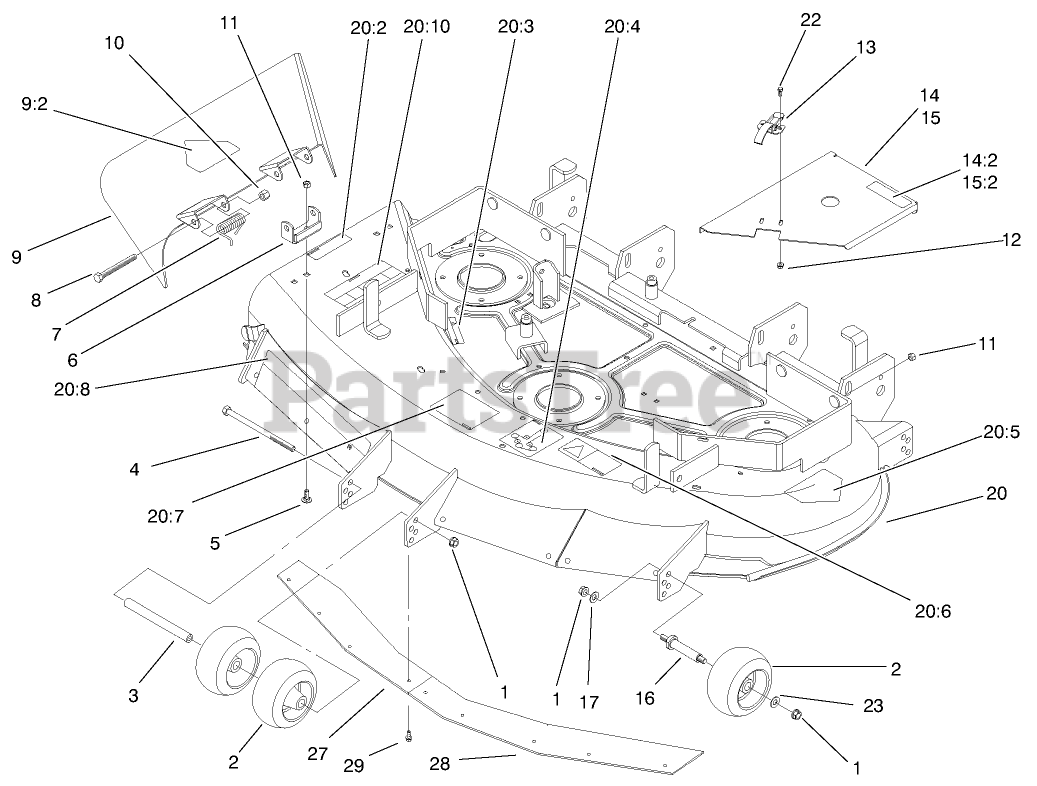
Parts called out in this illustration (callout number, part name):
1	NUT-HHF, WHIZ
2	WHEEL-GAGE
3	SPACER-WHEEL
4	SCREW-HH
5	SCREW-CARR
6	BRACKET-PIVOT
7	SPRING
8	SCREW-HH
9	DISCHARGE CHUTE W/DECAL-CE
9:2	DECAL-DANGER
10	NUT-HEX
11	NUT-LOCK, CONE
12	NUT-LOCK, FLANGE
13	CLAMP-SLOTTED
14	LH COVER ASM
14:2	DECAL-WARNING
15	RH COVER ASM
15:2	DECAL-WARNING
16	SPACER
17	Washer
20	44" DECK ASM W/DECALS-INTL
20:2	DECAL-WARNING, DEFLECTOR
20:3	DECAL-WARNING
20:4	DECAL-ROUTING, BELT
20:5	DECAL-DANGER
20:6	DECAL-TORQUE, BLADE BOLT
20:7	DECAL-ANTI SCALP
20:10	DECAL-DANGER
22	SCREW-HWH
23	Washer
27	PLATE-BLOWOUT, RH
28	PLATE-BLOWOUT, LH
29	SCREW
